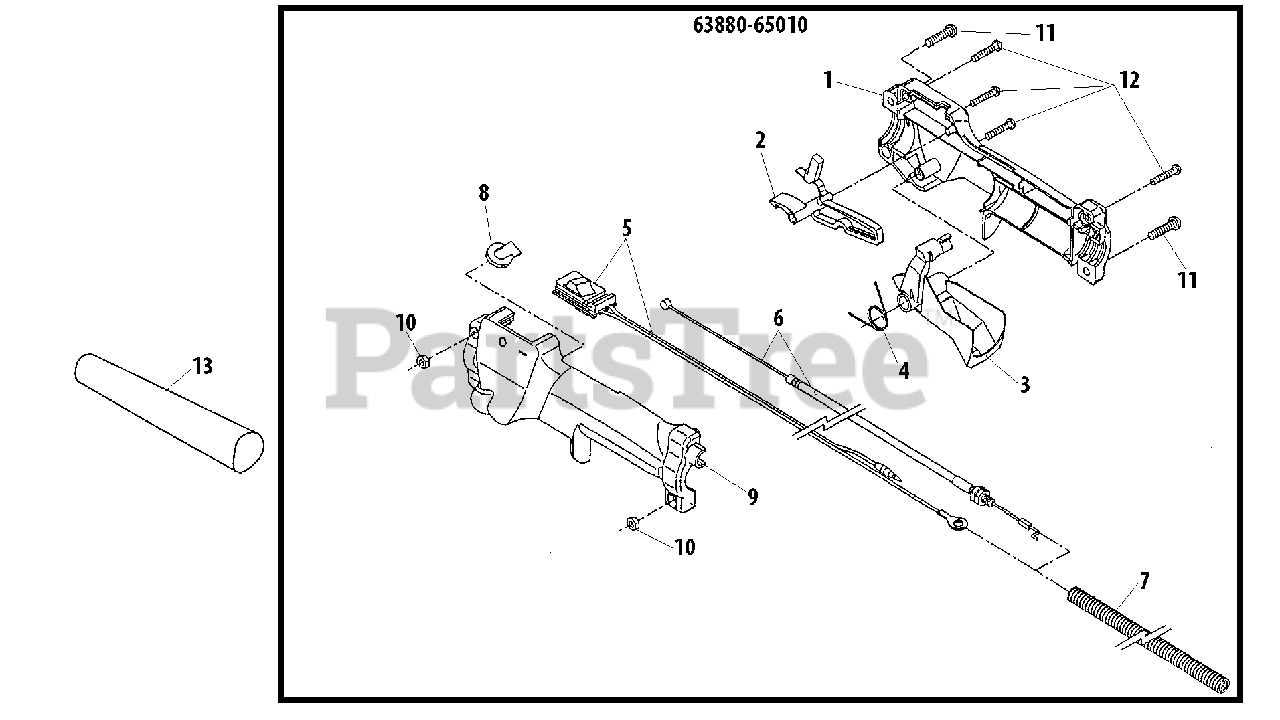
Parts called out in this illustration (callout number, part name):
1	HANDLE, CONTROL - RIGHT
2	LEVER, LOCK
3	LEVER
4	SPRING
5	SWITCH, IGNITION
6	CABLE, THROTTLE
7	TUBE
8	PLUG
9	HANDLE, CONTROL - LEFT
10	NUT - 5
11	SCREW - 5X20
12	SCREW - 4X20 -- TAPPING
13	COLLAR
